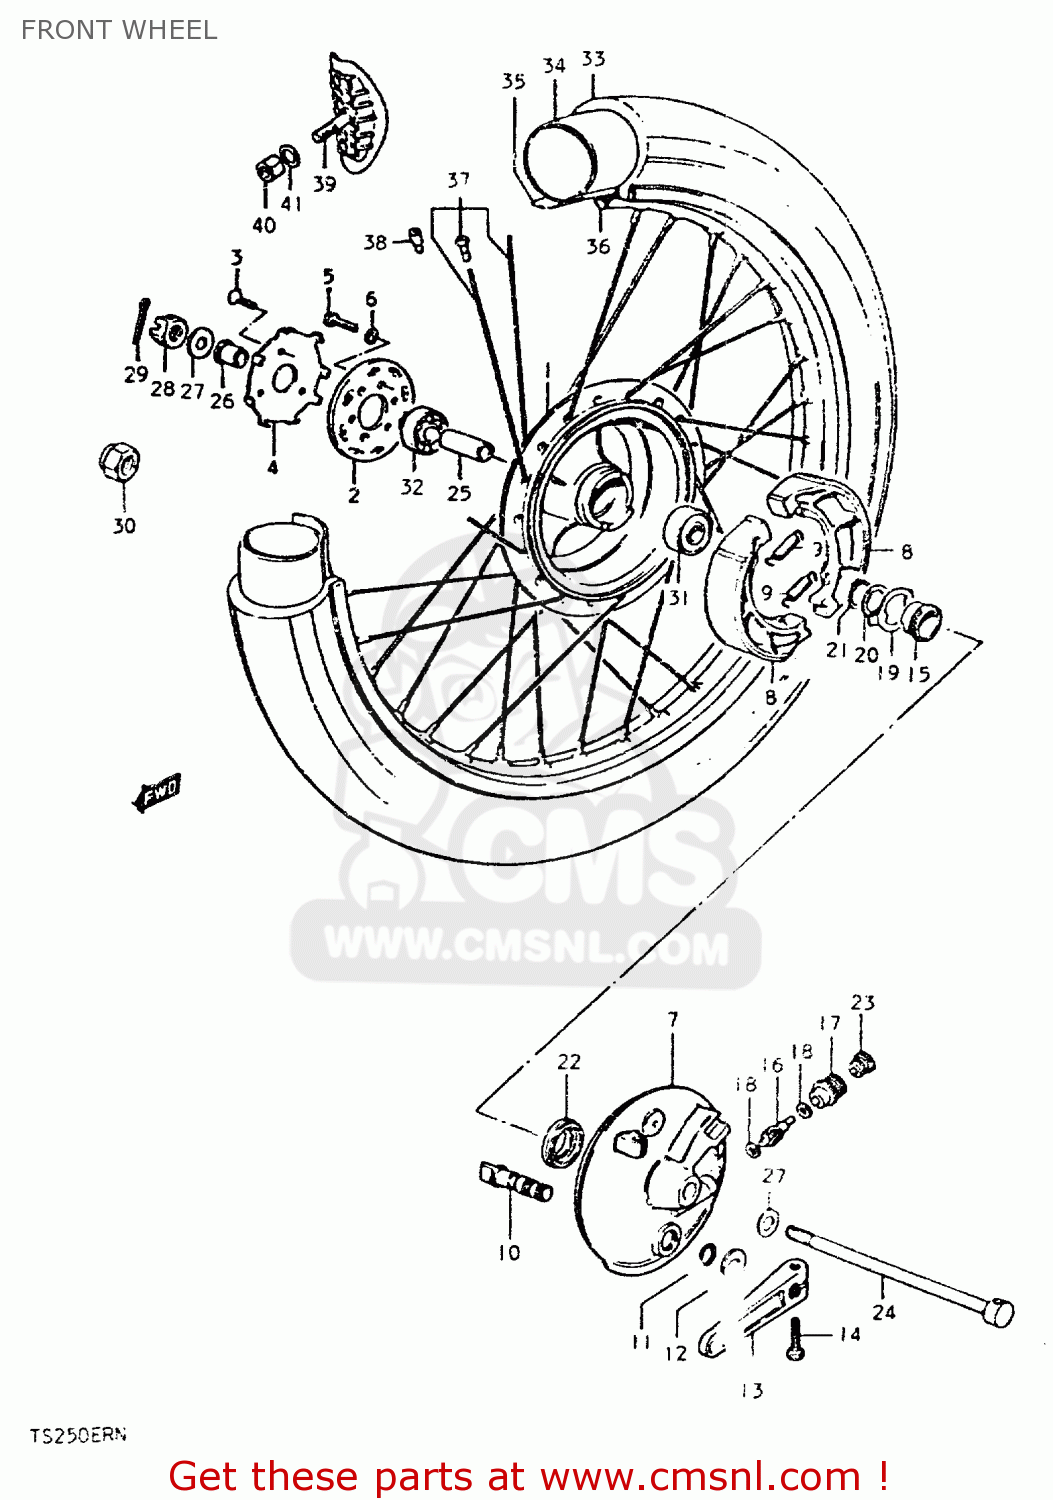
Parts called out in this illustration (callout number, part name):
1	DRUM,FRONT HUB
2	FLANGE,FR HUB,R
3	SCREW
4	RETAINER,FR HUB BEARING,R
5	BOLT, UPPER
6	LOCK WASHER
7	PANEL,FRONT HUB
8	SHOE,BRAKE (MCA)
9	SPRING
10	CAM,FRONT BRAKE
11	O-RING,BOSS
12	WASHER (15X24X1.6)
13	LEVER,FRONT BRAKE CAM
14	BOLT
15	GEAR,SPEEDOMETER
16	PINION,SPEEDOMETER
17	BUSHING,SPEEDOMETER PINION
18	WASHER (5.1X9X0.4)
19	DRIVER,SPEEDOMETER GEAR
20	WASHER(22.5X27X1)
21	CIRCLIP
22	SEAL,OIL(26X38X4)
23	SEAL,OIL(6X10X3)
24	AXLE,REAR
25	SPACER (12.6X19X52)
26	SPACER,FR AXLE,R
27	WASHER
28	NUT, REAR AXLE
29	COTTER PIN
31	BEARING
32	BEARING, RH
33	TIRE,FRONT
34	TUBE
35	PROTECTOR,WHEEL,INNER
36	RIM,FRONT WHEEL
37	SPOKE SET,FRONT
38	BALANCER,WHEEL (50G)
39	STOPPER,BEAD
40	NUT
41	WASHER
